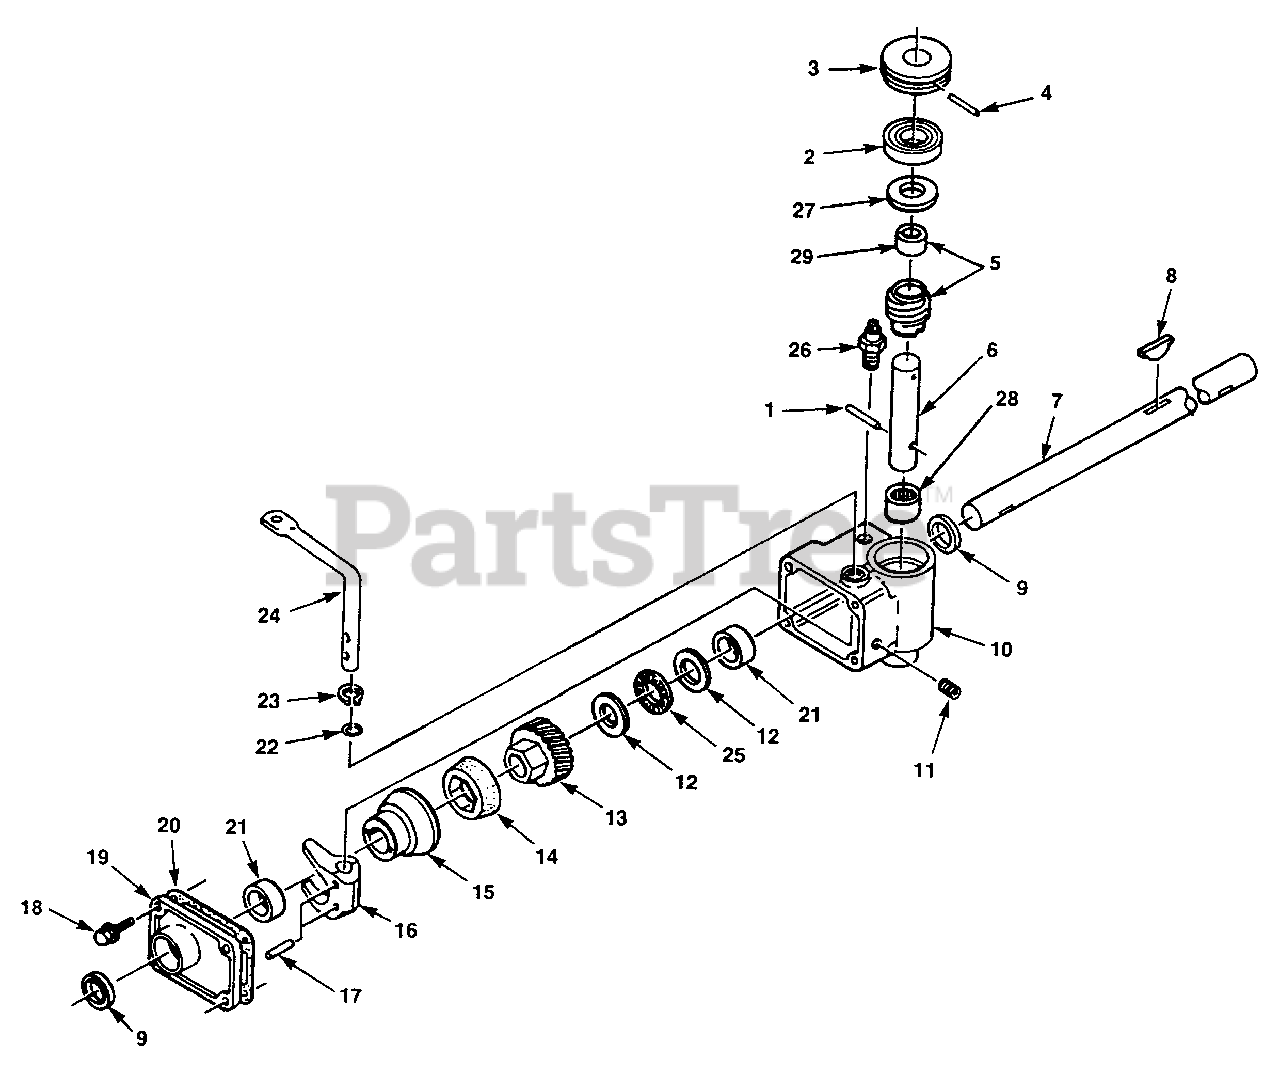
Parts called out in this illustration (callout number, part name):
3	PULLEY
5	WORM & SPACER
6	SHAFT- Worm
7	SHAFT- Drive
10	GEAR REDUCER HOUSING ASSY.
12	RACE- Bearing
13	GEAR- Helical
14	CONE- Friction
15	DRUM- Clutch
16	FORK- Shift
18	SCREW- Sems hd. 1/4-20 x 7/8
19	COVER- Gearbox
20	GASKET
21	BUSHING- Sleeve
24	LEVER- Shift
25	BEARING- Thrust
28	BEARING- Needle
